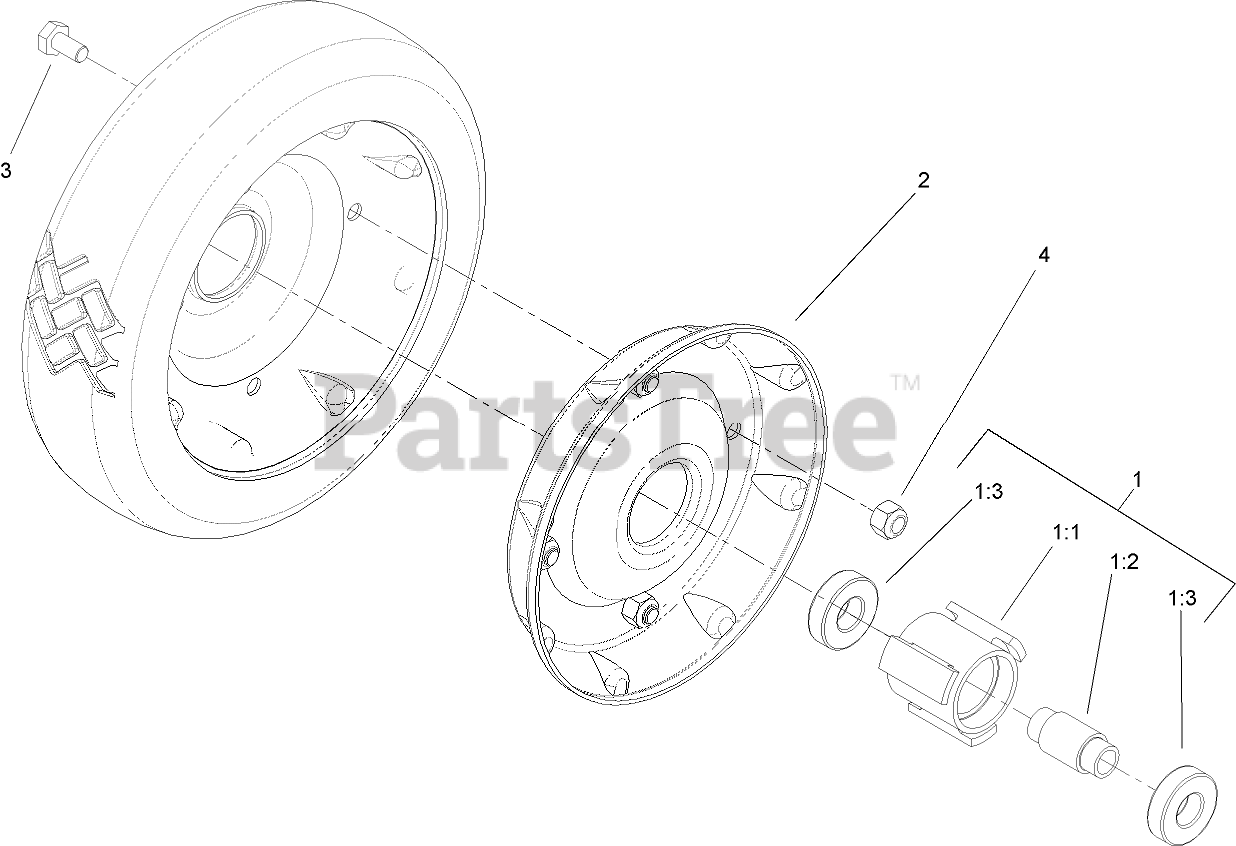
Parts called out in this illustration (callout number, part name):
1	HUB and BEARING ASM
1:1	HUB-BEARING
1:2	SPACER-BEARING
1:3	BEARING-WHEEL
2	PLATE-WHEEL, HALF
3	SCREW-HH
4	NUT-LOCK, NI
